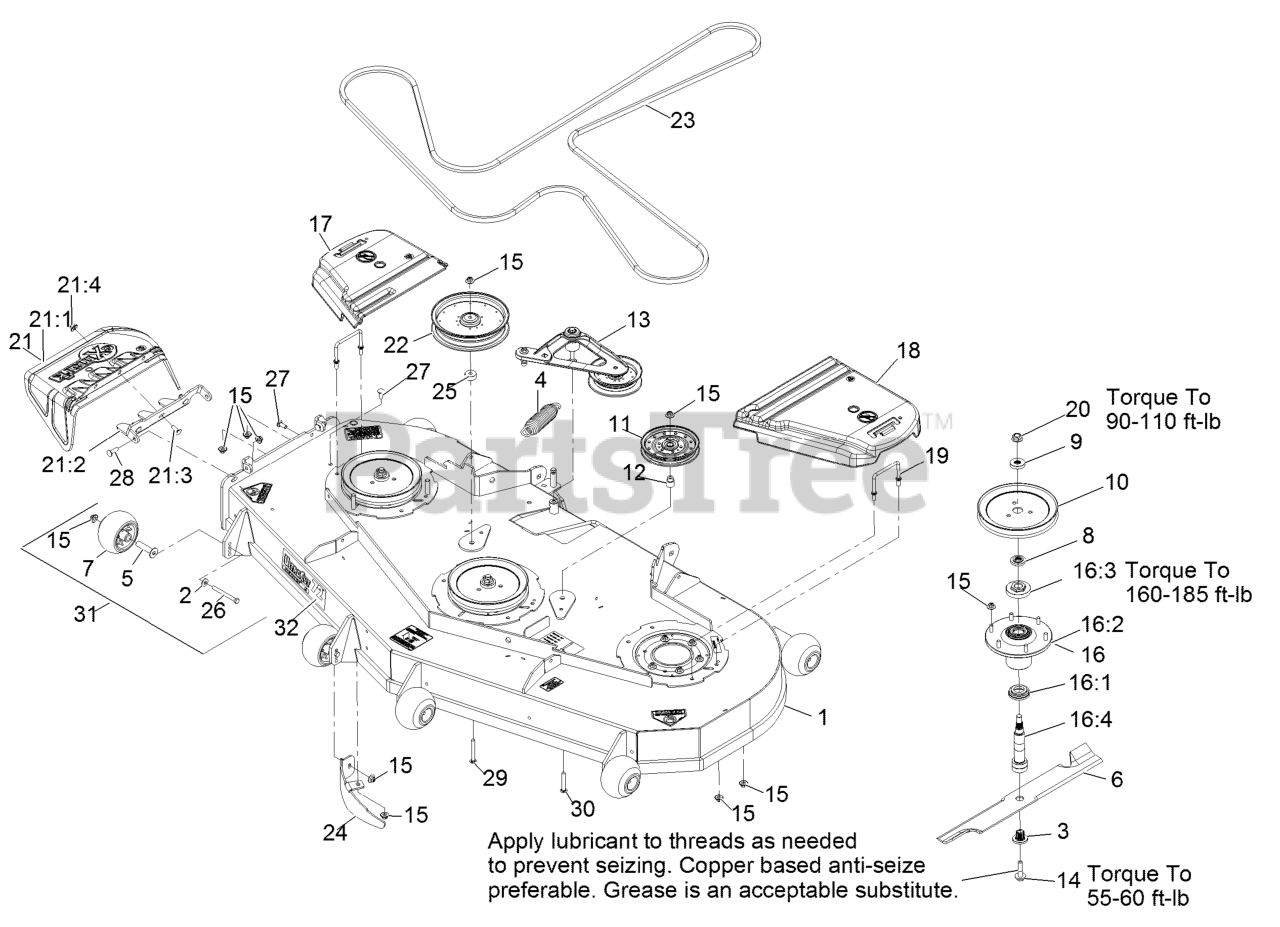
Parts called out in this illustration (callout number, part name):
1	DECK W/ DECALS ASM-72
2	WASHER-BELLEVILLE
3	BUSHING,SPLINED
4	SPRING-EXTENSION
5	AXLE, ROLLER
7	ROLLER-SCALP, ANTI
8	SPACER,SPLINED STEPPED
9	SPACER,SPLINED
10	SHEAVE,BLADE DRIVE 9.00
12	BUSHING-IDLER
13	DECK IDLER ASM
14	SCREW,SEMS 1/2-20 X 2.19
15	Nut-Nyloc 3/8-16 Flg
16	ASM,SPINDLE HOUSING
16:1	GUARD,BOTTOM
16:2	ASM,CUTTER HOUSING
16:3	NUT, SPINDLE 7/8-14
16:4	SPINDLE,DOUBLE SPLINE
17	COVER-BELT, RH
18	COVER-BELT, LH
19	WIREFORM-COVER
20	NUT-FLANGE, CENTERLOCK
21	ASM,DISCHARGE CHUTE
21:1	CHUTE,DISCHARGE
21:2	BRACKET,DISCHARGE CHUTE
21:3	SCREW-CARR
21:4	Nut-Nyloc 3/8-16 Flg
22	PULLEY-IDLER
23	BELT-V
24	BAFFLE-DOGLEG, LZ72
25	SPACER-IDLER
26	SCREW-HH 3/8-16 X 3 3/4 GR 8
27	SCREW-CARR
28	Bolt-Carriage 3/8-16 X 1 1/4
29	SCREW-CARR
30	SCREW-CARR
31	KIT, ANTI-SCALP ROLLER
32	DECAL,ULTRACUT 72 SERIES
